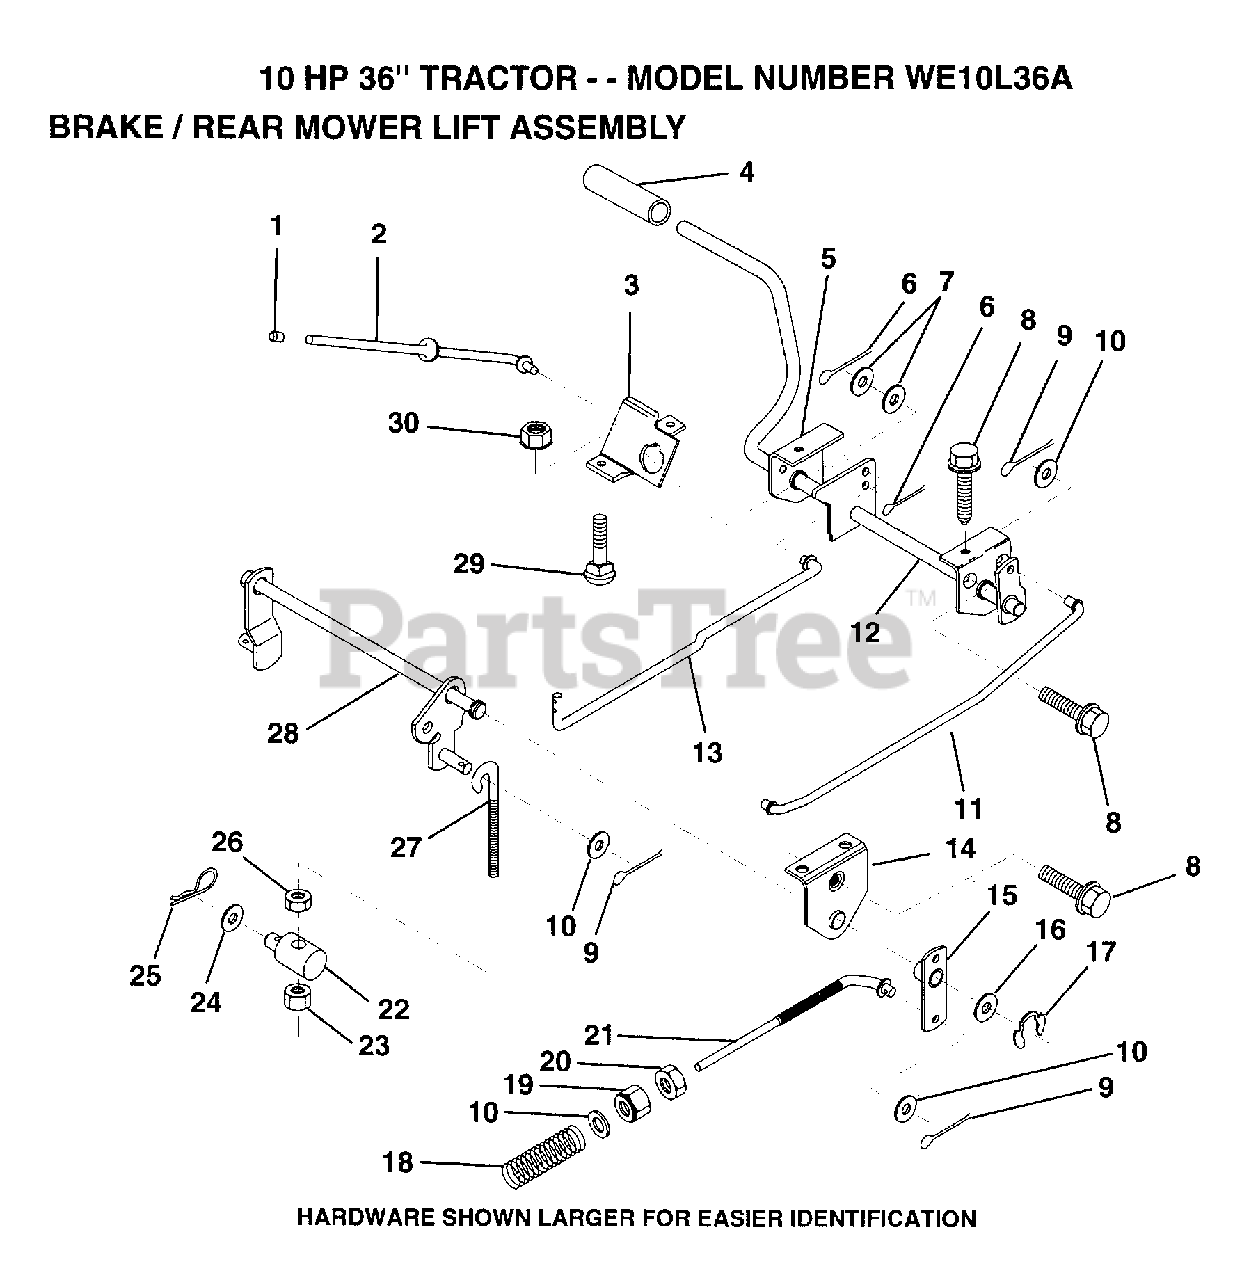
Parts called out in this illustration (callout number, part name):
1	PLUNGER CAP T
2	"ROD,PARK BRAKE"
3	"BRKT,PARK BRAKE"
4	FOOT PEDAL COVER
5	"BRKT,CLU PEDAL LH"
7	WASHER
8	SCREW LT
9	COTTER PIN
10	WASHER
11	"ROD,FRT BRAKE"
13	"ROD,CLUTCH"
14	"BRKT,LIFT SHAFT"
15	BRAKE PIVOT ARM
16	WASHER T
17	KLIP RING
18	SPRING ROD LT
19	NUT
20	NUT
21	ROD.BRAKE.REAR
24	WASHER
25	SPRING.RETAINER
26	LOCKNUT
27	"LINK, MOWER REAR"
